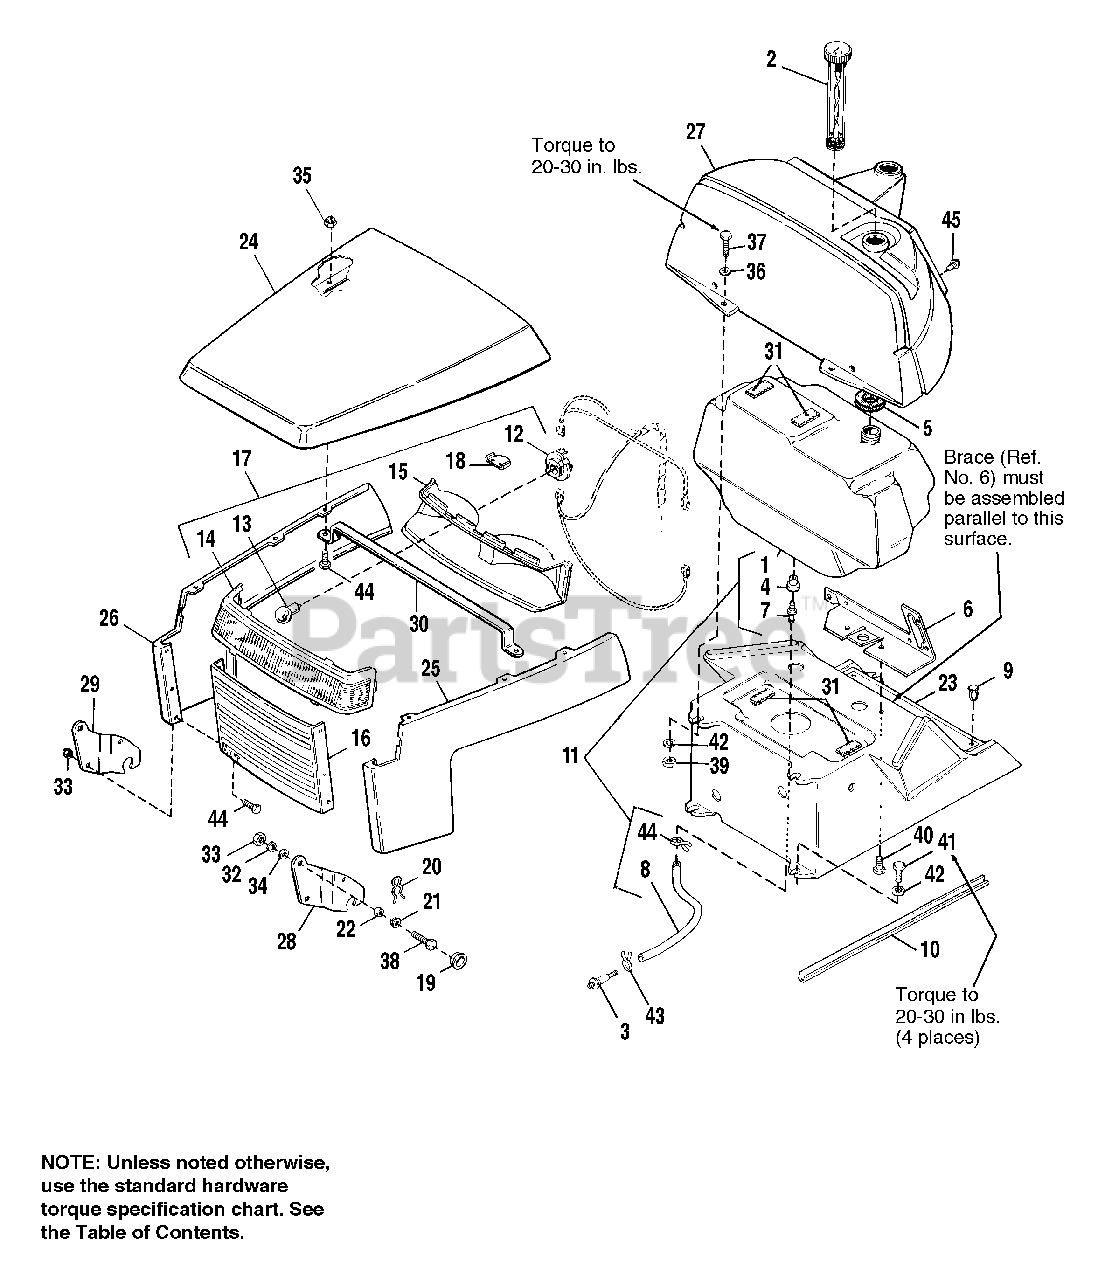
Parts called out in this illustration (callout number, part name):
2	CAP, Fuel Tank
3	FILTER, Fuel
5	WASHER, Foam
8	HOSE, Fuel
9	CLIP, Canoe
10	EDGING, Lower Dash
11	TANK ASSY., Fuel
12	SOCKET, Bulb, Headlight
13	BULB, Headlight, 12.8V
14	LENS, Headlight
15	BEZEL, Headlight
16	GRILLE
17	HEADLIGHT ASSY.
18	HEAT SHIELD, Headlight
19	SPACER, Hood
20	CLIP, Hairpin
21	PIVOT, Hood
23	DASHBOARD, Bottom
24	HOOD, Orange
25	SIDE PANEL, LH, Orange
25	SIDE PANEL, LH, Red
26	SIDE PANEL, RH, Orange
26	SIDE PANEL, RH, Red
27	DASHBOARD, Top
30	BAR-TIE, Hood
32	LOCKWASHER, 5/16
33	NUT, Hex, 5/16-18
34	WASHER, Plain 5/16
35	NUT, Hex, Nylon-lock, 1/4-20
36	WASHER, 1/4, std.
37	CAPSCREW, Hex, 1/4-20 x 1-1/4
38	CAPSCREW, Hex Hd., 5/16-18 x 1-1/4
39	LOCKNUT, Hex, 1/4-20
40	SCREW, Taptite, 1/4-20 x 3/4
41	SCREW, Taptite, 1/4-20 x 1
42	LOCKWASHER, Dish, 1/4
43	CLAMP, Hose
44	SCREW, Hex, Whizlock, 1/4-20 x 5/8
45	SCREW, Hex , Washer Hd., 1/4-20 x 5/8
